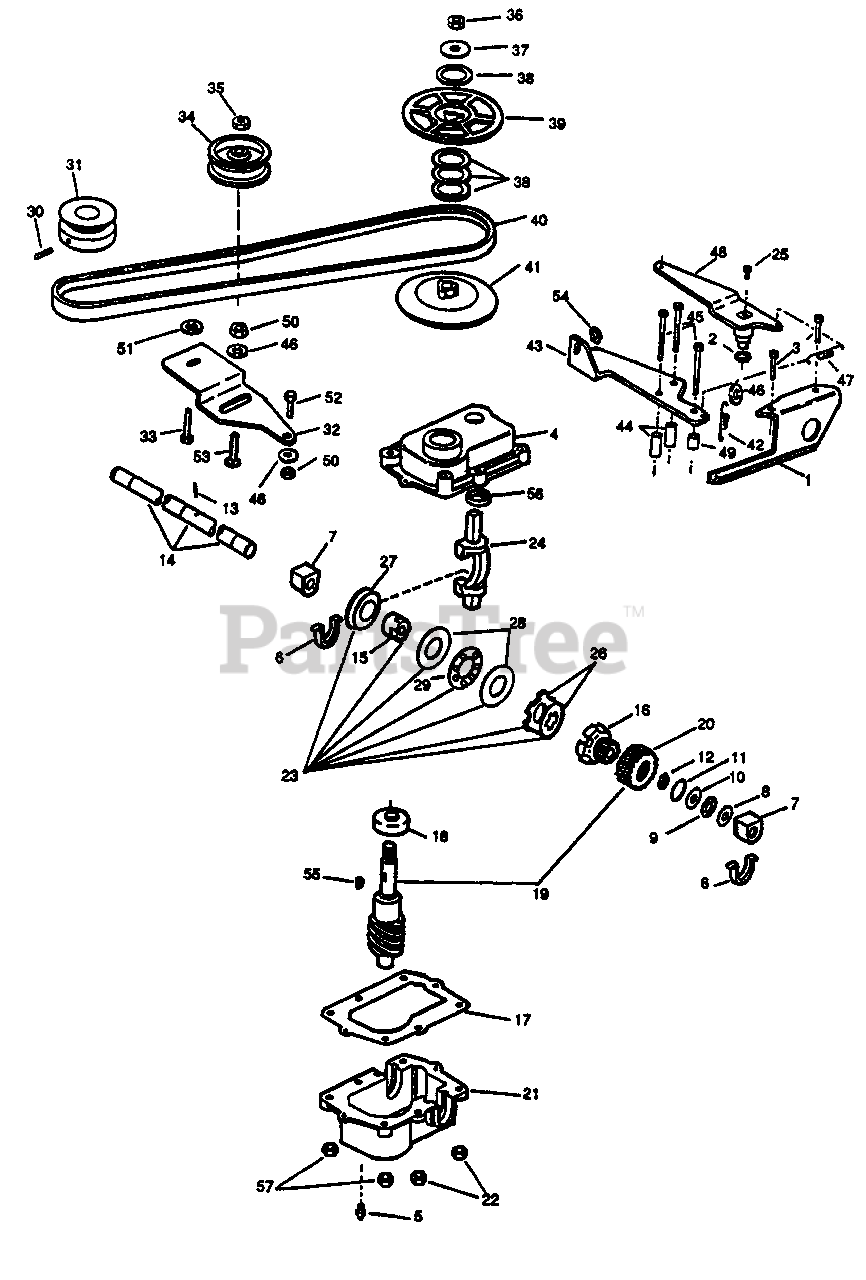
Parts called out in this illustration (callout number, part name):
1	Tensioner Bracket
2	O-Ring
3	Hex Hd. Cap Screw
4	Gearcase-Upper
5	Plug
6	Packing
7	Bearing & Seal-Gearcase
8	Thrust Washer
9	Thrust Bearing
10	Thrust Washer
11	Thrust Washer
12	Retaining Ring
13	Pin
14	Driveshaft
15	Driven Sleeve
16	Driver
17	Gasket
18	Bearing
19	Worm Wheel & Shaft (Inc. 20)
20	Worm Wheel
21	Gearcase-Lower
22	Nut, Lock
23	Collar, Brg & Disc Kit (Inc. 24-29)
24	Shift Fork
25	Screw
26	Disc Plate Kit
27	Collar
28	Thrust Washer
29	Bearing
30	Set Screw
31	Pulley-Engine
32	Bracket & Idler Assy (Inc. 33-35)
33	Screw
34	Pulley-Idler
35	Nut
36	Nut
37	Washer
38	Washer
39	Pulley-Upper Half
40	V-Belt
41	Pulley-Lower Half
42	Ezeension Spring
43	Conduit Anchor Bracket
44	Spacer
45	Screw
46	Washer
47	Extension Spring
48	Shift Arm & Hub Assembly
49	Spacer
50	Nut
51	Washer
52	Screw
53	Square Neck Bolt
54	Retaining Ring
55	Key
56	Seal Guide
57	Nut-Lock
